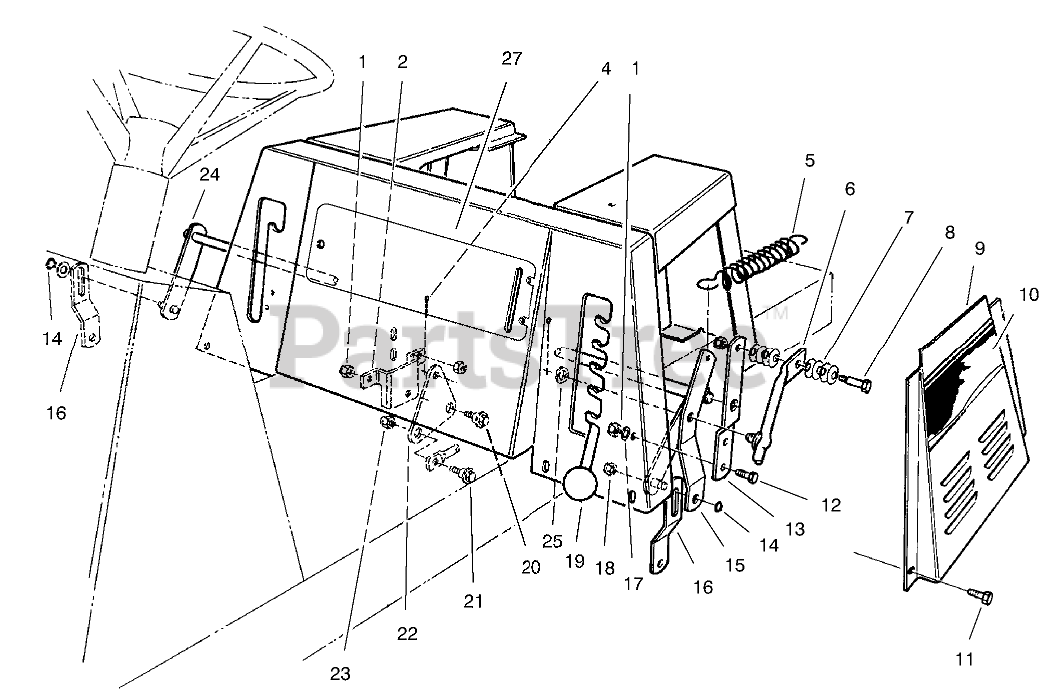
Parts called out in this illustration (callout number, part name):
1	NUT-LOCK, NI
2	BRKT-B.CRANK MTG
4	PIN-COTTER
5	SPRING-EXTENSION
6	HOC LEVER WA (BLACK)
7	WASHER-BELLEVILLE
8	BOLT-SHOULDER
9	PANEL-LH SEAT BASE
10	DECAL - SIDE
11	SCREW-HH
12	SCREW-HH
13	BRKT-HOC SUPT
14	RING-RETAINING
15	BRKT-HOC ENGAGE
16	LINK-SUSP
17	WASHER-PLAIN
18	NUT-LOCK, NI
20	SCREW-SHOULDER
21	SCREW-SHOULDER
22	BELLCRANK
23	NUT-HEX
24	HOC LEVER WA (BLACK)
25	WASHER-FLAT
27	DECAL-CONTROL PANEL
